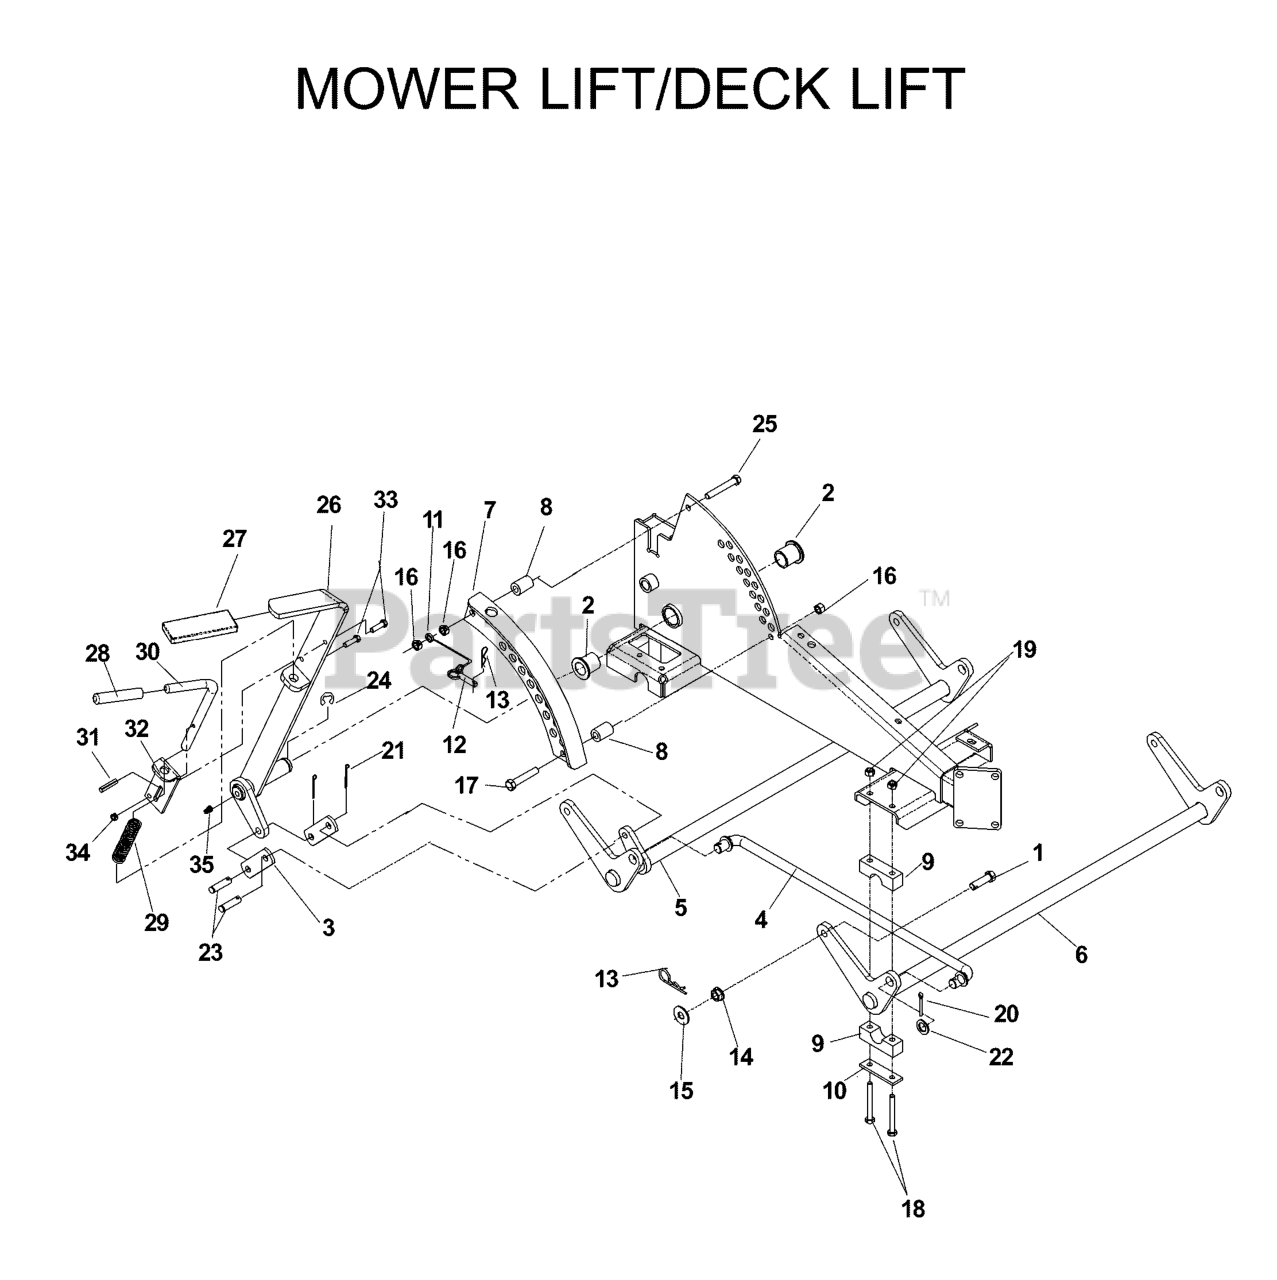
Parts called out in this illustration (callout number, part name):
1	HCS 7/16-14X1-1/2 GR5 ZD SPEC
2	BUSHING, FLANGED
4	CROSS LINK
5	REAR LIFT SHAFT
6	FRONT LIFT SHAFT
7	ADJUSTMENT PLATE WLDMT
8	DECK LIFT SPACER
9	PILLOW BLOCK
10	REINFORCEMENT BAR
13	HAIRPIN #4
14	NUT 7/16C WHIZ
15	WASHER 7/16 FLAT ZD
16	NUT 3/8-16 NYLOC
17	HCS 3/8C X 2 1/2
18	HCS 5/16C X 2-3/4
19	NUT 5/16 NYLOC
20	COTTER PIN
21	RP_COTTER PIN 1/8 X 3/4
23	CLEVIS PIN 3/8 X 1 1/8
24	E-RING 7/8
25	SCREW 3/8C X 2 3/4 HEX CAP
26	LIFT LEVER WELDMENT
32	PIN MT, UPPER
33	HCS 1/4C X 3/4 HCS
34	NUT 1/4C CENTER LOCK
